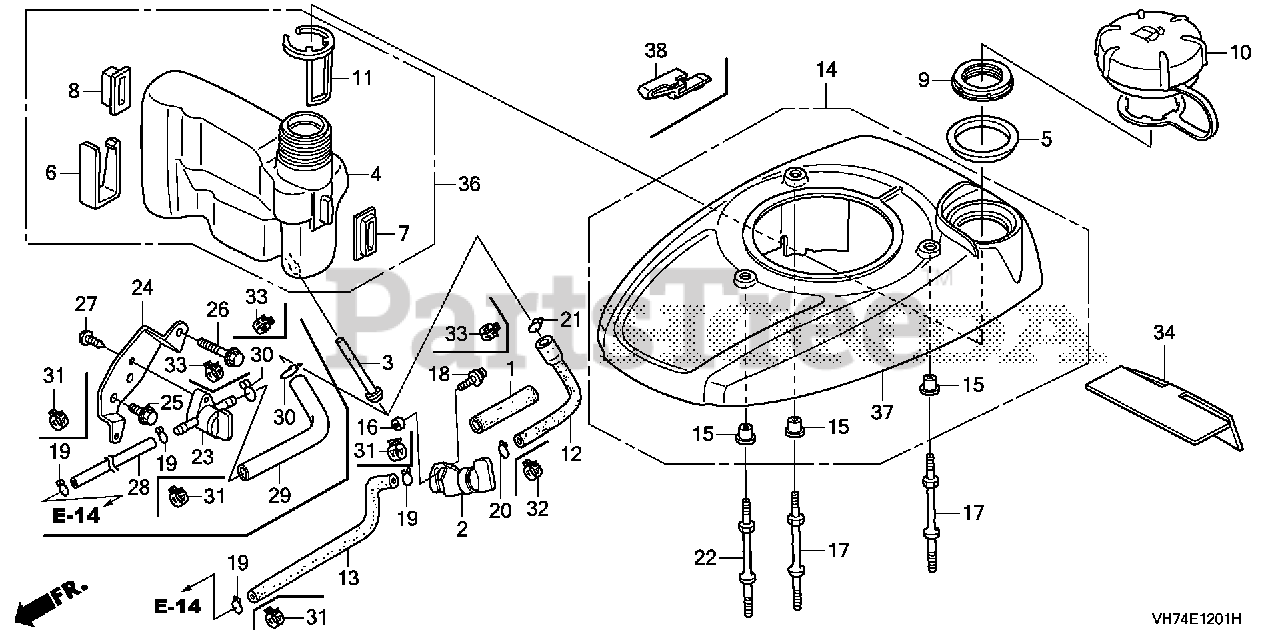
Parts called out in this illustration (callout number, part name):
1	RUBBER, SUPPORTER (107MM)
2	PETCOCK ASSY.
3	FILTER, FUEL
4	TANK, FUEL
5	SEAL, FUEL FILLER NECK
7	RUBBER A, TANK MOUNTING
8	RUBBER B, TANK MOUNTING
9	NUT, TANK MOUNTING
10	CAP ASSY., FUEL TANK
11	GAUGE, FUEL LEVEL
12	TUBE, FUEL TANK
13	TUBE, FUEL (FKM)
16	COLLAR, FUEL PETCOCK
17	BOLT, STUD (FAN COVER)
18	SCREW-WASHER (5X10)
22	BOLT, STUD (FAN COVER)
31	CLIP, TUBE (D8)
32	CLAMP, TUBE (D10)
33	CLAMP, TUBE (D12)
37	COVER, FAN *R280* (POWER RED)
38	CLIP, TANK MOUNTING *NH1* (BLACK)
